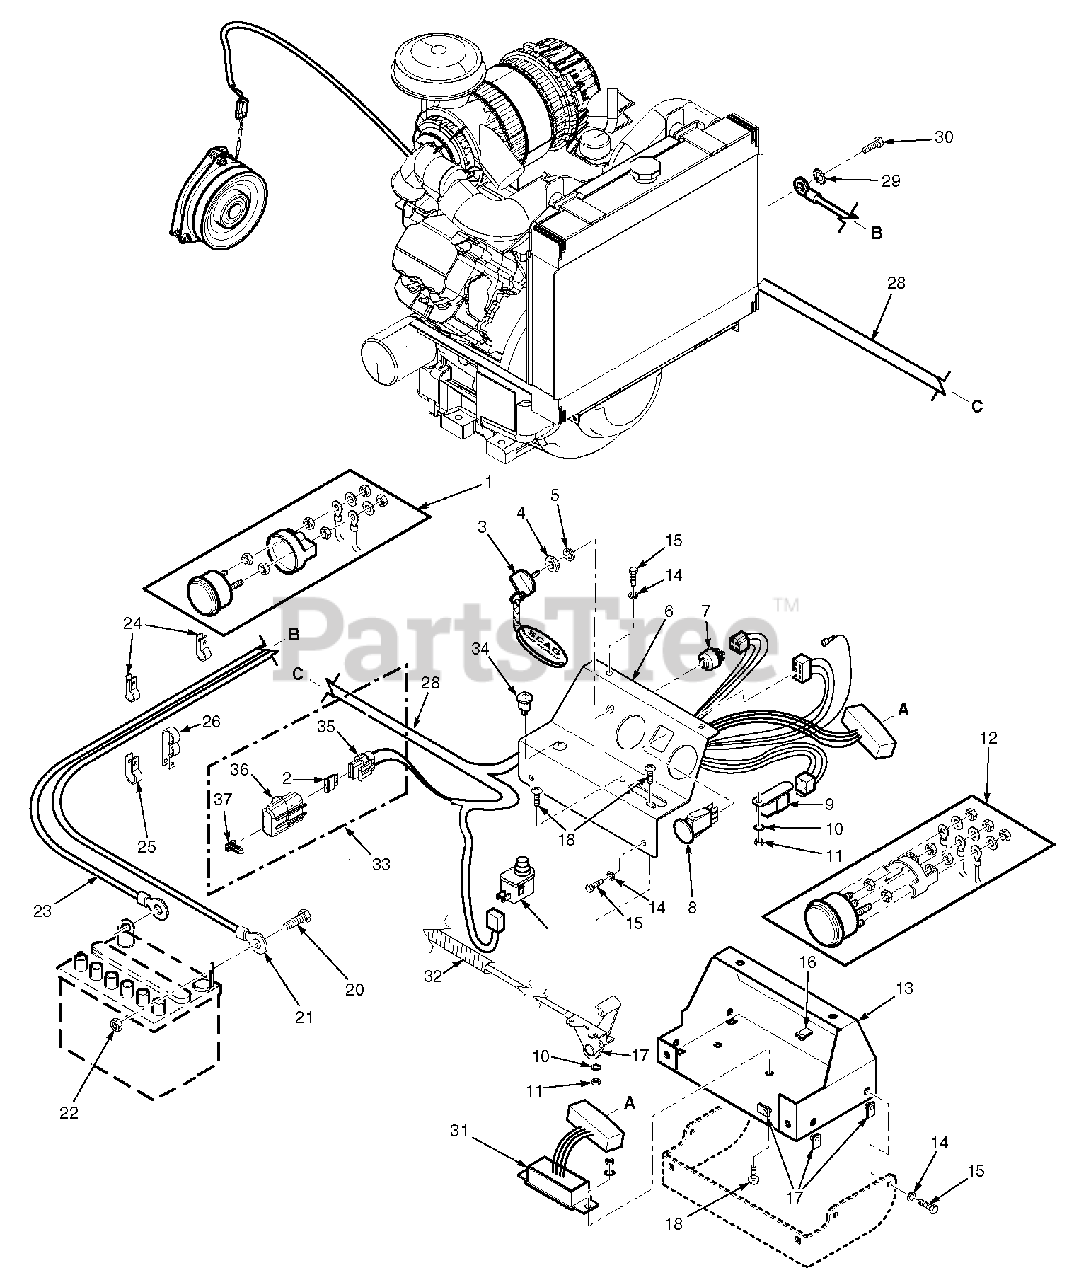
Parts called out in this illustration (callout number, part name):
1	Volt Meter
2	Fuse, 20 AMP
3	Key, Assembly w/Fob
4	Nut, Hex 5/8-32
5	Lockwasher, 5/8" Internal
6	Instrument Panel, Top w/Decals
7	Key Switch
8	Switch, PTO - 10 Amp
9	Relay
10	Lockwasher, #10 External Tooth
11	Nut, Hex #10-32
12	Water Temp. Gauge
13	Base, Instrument Panel
14	Lockwasher, 1/4"
15	Bolt, Hex Hd. 1/4-20 x 3/4"
16	U-Nut, 1/4-20
17	Throttle Controls
18	Screw, Phillips Washer Head #10-32 x 1/2"
19	Switch, Interlock-Seat
20	Bolt, Hex Hd. 1/4-20 x 1/2"
21	Cable, Battery - Red
22	Nut, Hex 1/4-20
23	Cable, Battery - Black
24	Clamp, Cable 1/2" I.D.
25	Clamp, Cable 3/4" I.D.
26	Clamp, Cable
27	Sending Unit, Water Temp.
28	Wire Harness, STT Liquid-Cooled Electronic Fuel Injection (EFI)
29	Lockwasher, 5/16" External Tooth
30	Bolt, Hex Hd. M8-1.25 x 20mm
31	Electronic Module
32	Heatshield, Flexible
33	Single Fuse Assembly, Sealed
34	Indicator Light, Check Engine
35	Fuse Holder
36	Cover, Sealed Single
37	Clip, Wire
